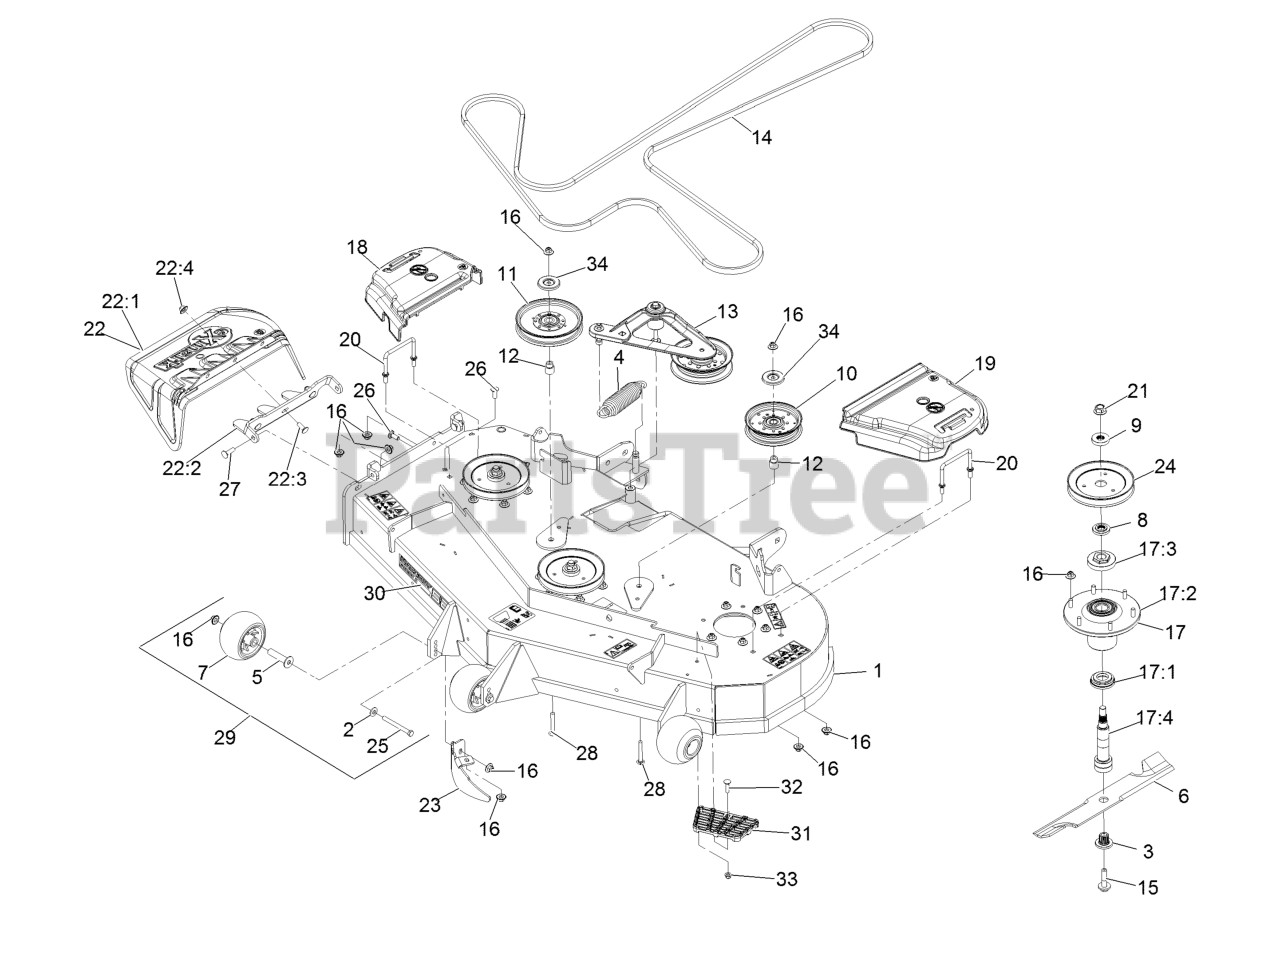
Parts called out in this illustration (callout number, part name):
1	ASM,DECK W/ DECALS 52
2	WASHER-BELLEVILLE
3	BUSHING,SPLINED
4	SPRING-EXTENSION
5	AXLE, ROLLER
7	ROLLER-SCALP, ANTI
8	SPACER,SPLINED STEPPED
9	SPACER,SPLINED
10	PULLEY-IDLER, FLAT
11	IDLER-PULLEY
12	BUSHING-IDLER
13	DECK IDLER ASM
14	BELT,V-B X 186.00"
15	SCREW,SEMS 1/2-20 X 2.19
16	Nut-Nyloc 3/8-16 Flg
17	ASM,SPINDLE HOUSING
17:1	GUARD,BOTTOM
17:2	ASM,CUTTER HOUSING
17:3	NUT, SPINDLE 7/8-14
17:4	SPINDLE,DOUBLE SPLINE
18	COVER-BELT, RH
19	COVER-BELT, LH
20	WIREFORM-COVER
21	NUT-FLANGE, CENTERLOCK
22	ASM,DISCHARGE CHUTE
22:1	CHUTE,DISCHARGE
22:2	BRACKET,DISCHARGE CHUTE
22:3	SCREW-CARR
22:4	Nut-Nyloc 3/8-16 Flg
23	BAFFLE-DOGLEG, LZ-VT52
24	SHEAVE,BLADE DRIVE
25	SCREW-HH 3/8-16 X 3 3/4 GR 8
26	SCREW-CARR
27	Bolt-Carriage 3/8-16 X 1 1/4
28	SCREW-CARR
29	KIT, ANTI-SCALP ROLLER
30	Decal, 526
31	STEP-DECK
32	Bolt-Carriage 5/16-18 X 1 1/4
33	NUT-HF, NI
34	SHIELD-DUST
